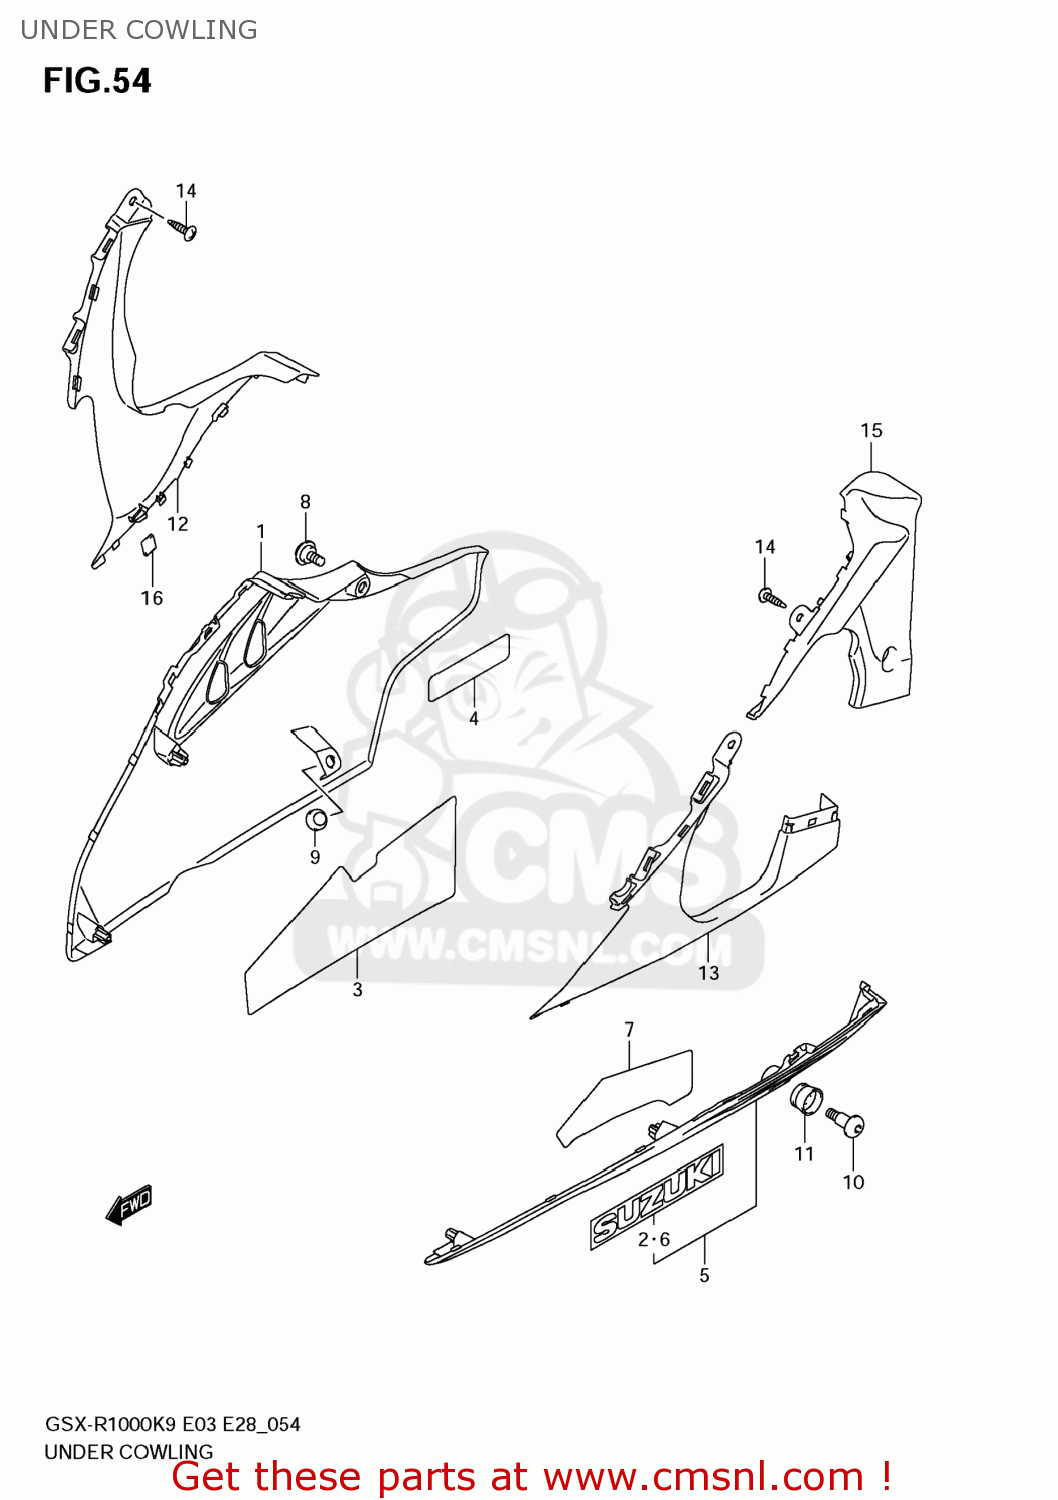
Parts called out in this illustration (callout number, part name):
1	COWLING,UNDER,R(BLACK)
2	EMBLEM,SUZUKI
3	SHIELD,UNDER COWL HEAT,R
4	SHIELD,HEAT
5	COWLING,UNDER,L(BLACK)
6	EMBLEM,SUZUKI,L
7	SHIELD,UNDER COWL HEAT,L
8	SCREW(5X13)
9	CUSHION
10	SCREW(6X20)
11	CUSHION,UNDER COWLING,L
12	COWLING,SIDE LWR,R
13	COWLING,SIDE LWR,L
14	SCREW
15	COVER,SIDE COWL,L
16	CUSHION,RR COVER NO.2
